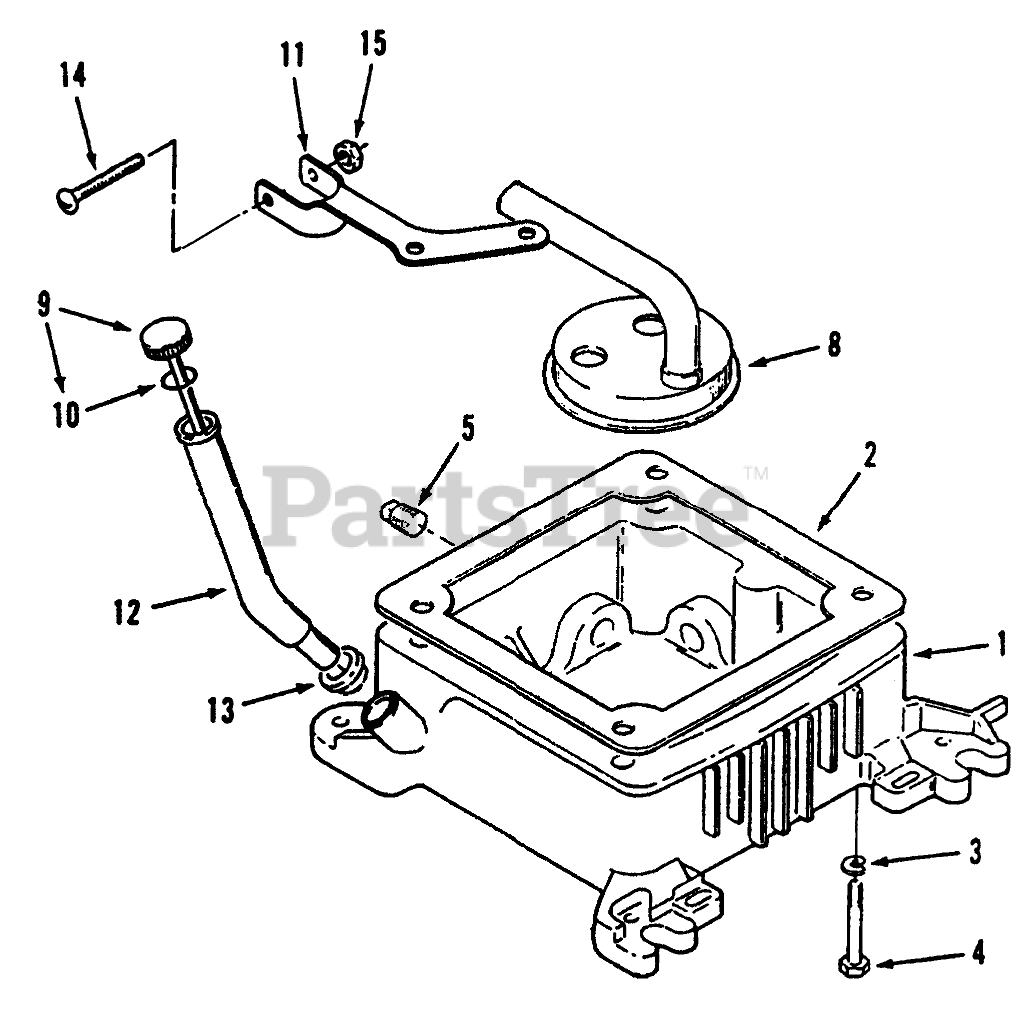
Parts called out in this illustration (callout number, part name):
1	Base-Oil (Incl. All Plugs & Plug Gasket)
2	GASKET
3	WASHER-FLAT
4	HHCS 3/8-16 X 3 3/4
5	PLUG - SQUARE HEAD
8	OIL CUP ASM
9	Cap-Oil Fill & Indicator (Incl. "O"Ring)
10	SEAL 0-RING
11	BRACKET-FILL TUBE
12	TUBE-OIL FILL
13	SEAL-OIL FILL TUBE
14	SCREW - PAN HEAD
15	NUT - SPEED
